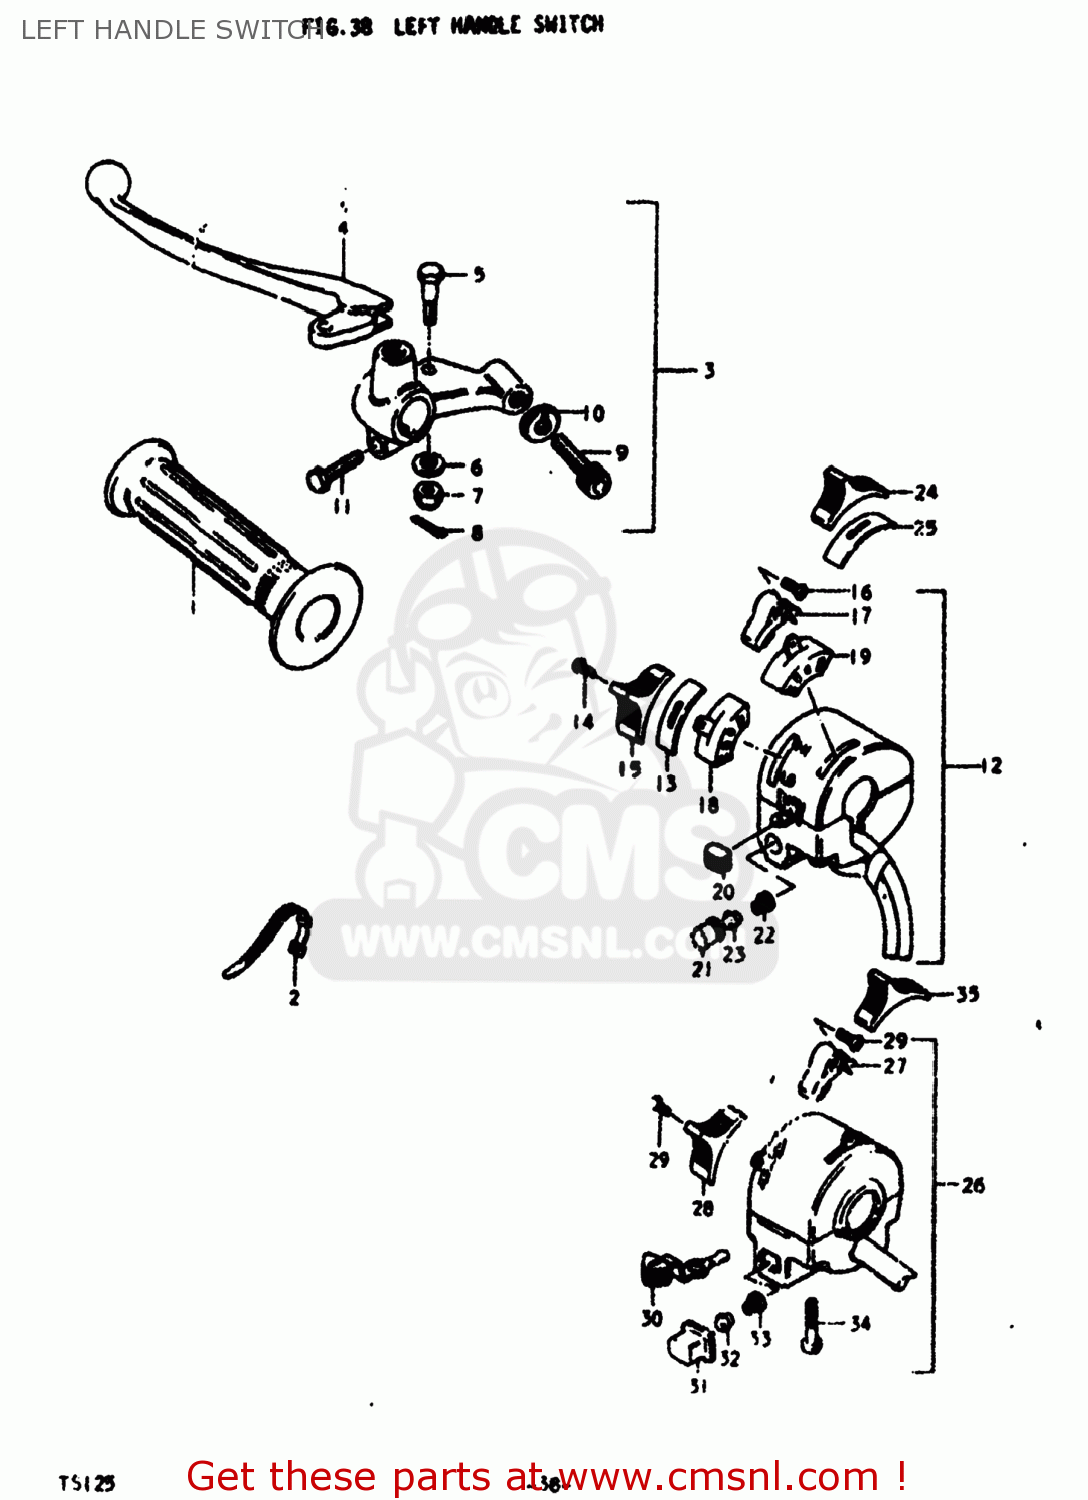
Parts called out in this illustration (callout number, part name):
1	GRIP,L
2	CLAMP(L:120)
3	ICATE) C
4	LEVER,CLUTCH
5	BOLT,LEVER
6	LOCK WASHER
7	NUT 6MM
8	COTTER PIN
9	ADJUSTER,CABLE
10	NUT,CABLE ADJUSTER
11	BOLT
12	SWITCH ASSEMBLY,HANDLE,LEFT
13	PLATE,DIMMER KNOB
14	SCREW, DIMMER
15	KNOB,HANDLE SWITCH,UPPER
16	SCREW
17	KNOB
18	SLIDING BLOCK, DIMMER SWITCH
20	KNOB,HANDLE SWITCH
21	BUTTON, HORN
22	SPRING,BUTTON
23	PLATE,HORN BUTTON
24	KNOB,HANDLE SWITCH
25	PLATE,LIGHTING KNOB
26	SWITCH ASSEMBLY,HANDLE,LEFT
27	KNOB,STOP
28	KNOB,DIMMER SWITCH
29	SCREW
30	KNOB,TURNSIGNAL
31	BUTTON,HORN
32	CONTACT
33	SPRING
34	SCREW
35	KNOB,LIGHTING SWITCH
